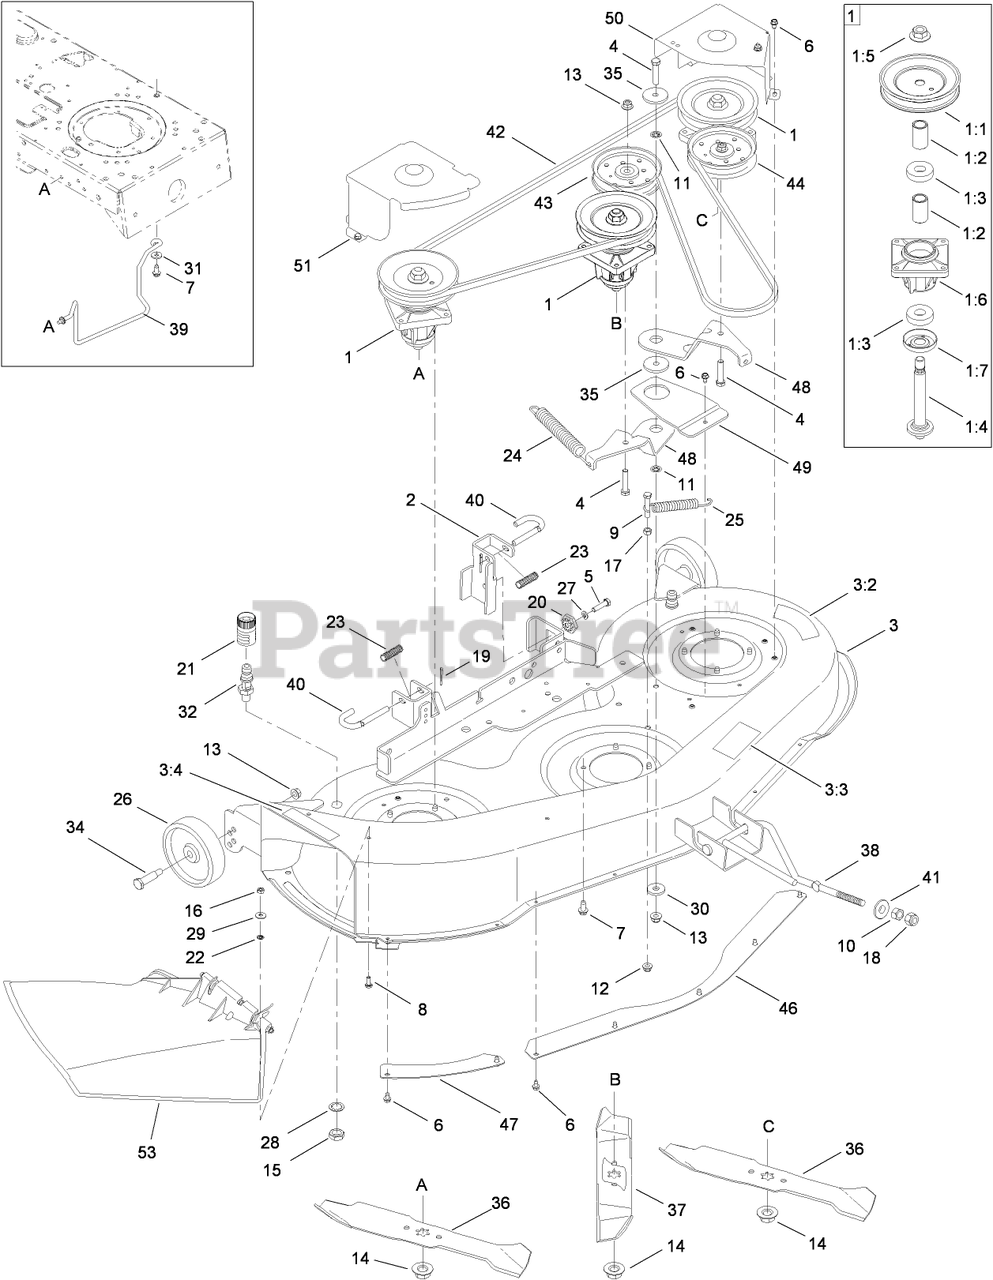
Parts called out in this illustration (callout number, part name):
1:1	PULLEY-DECK
1:2	SPACER
1:3	BEARING-BALL
1:5	NUT-LOCK, FLANGE
1:6	HOUSING-SPINDLE
1:7	BEARING-SHOULDER
2	LH HANGER BRACKET ASM
3	DECK ASM
3:2	DECAL-DANGER
3:3	DECAL-BELT ROUTING
3:4	DECAL-DANGER
4	SCREW-HH
5	SCREW-HH
6	SCREW-HWHTF
7	SCREW-HWH
8	SCREW-HH
9	SCREW-HH
10	NUT-HEX
11	NUT-PUSH
12	NUT-LOCK, FLANGE
13	NUT-LOCK, FLANGE
14	NUT-LOCK, FLANGE
15	NUT-HEX
16	NUT-HEX
17	NUT-HEX
18	NUT-LOCK, HEX (NYLON)
19	PIN-COTTER
20	GEAR-ADJUSTMENT, DECK
21	ADAPTER-NOZZLE, WATER
22	RETAINER-BOLT
23	SPRING-COMPRESSION
24	SPRING-EXTENSION
25	SPRING-EXTENSION
26	WHEEL-DECK, REAR
27	WASHER-LOCK
28	WASHER-LOCK
29	WASHER-SPRING
30	WASHER-FLAT
31	WASHER-FLAT
32	NOZZLE-WATER, DECK
34	BOLT-SHOULDER
35	SPACER-SHOULDER
36	BLADE-16.28 INCH
37	BLADE-14.88 INCH
38	ROD-DECK
39	ROD-KEEPER, BELT
40	PIN-HANDLE, DECK RELEASE
41	CUP-PIVOT, LIFT
42	BELT-TYPE A
43	PULLEY-IDLER
44	PULLEY-IDLER, 3.50 INCH
46	SKIRT-CENTER, DECK
47	SKIRT-RH, DECK
48	BRACKET-IDLER
49	BRACKET-SUPPORT
50	COVER-BELT
51	COVER-BELT
53	DISCHARGE CHUTE ASM
